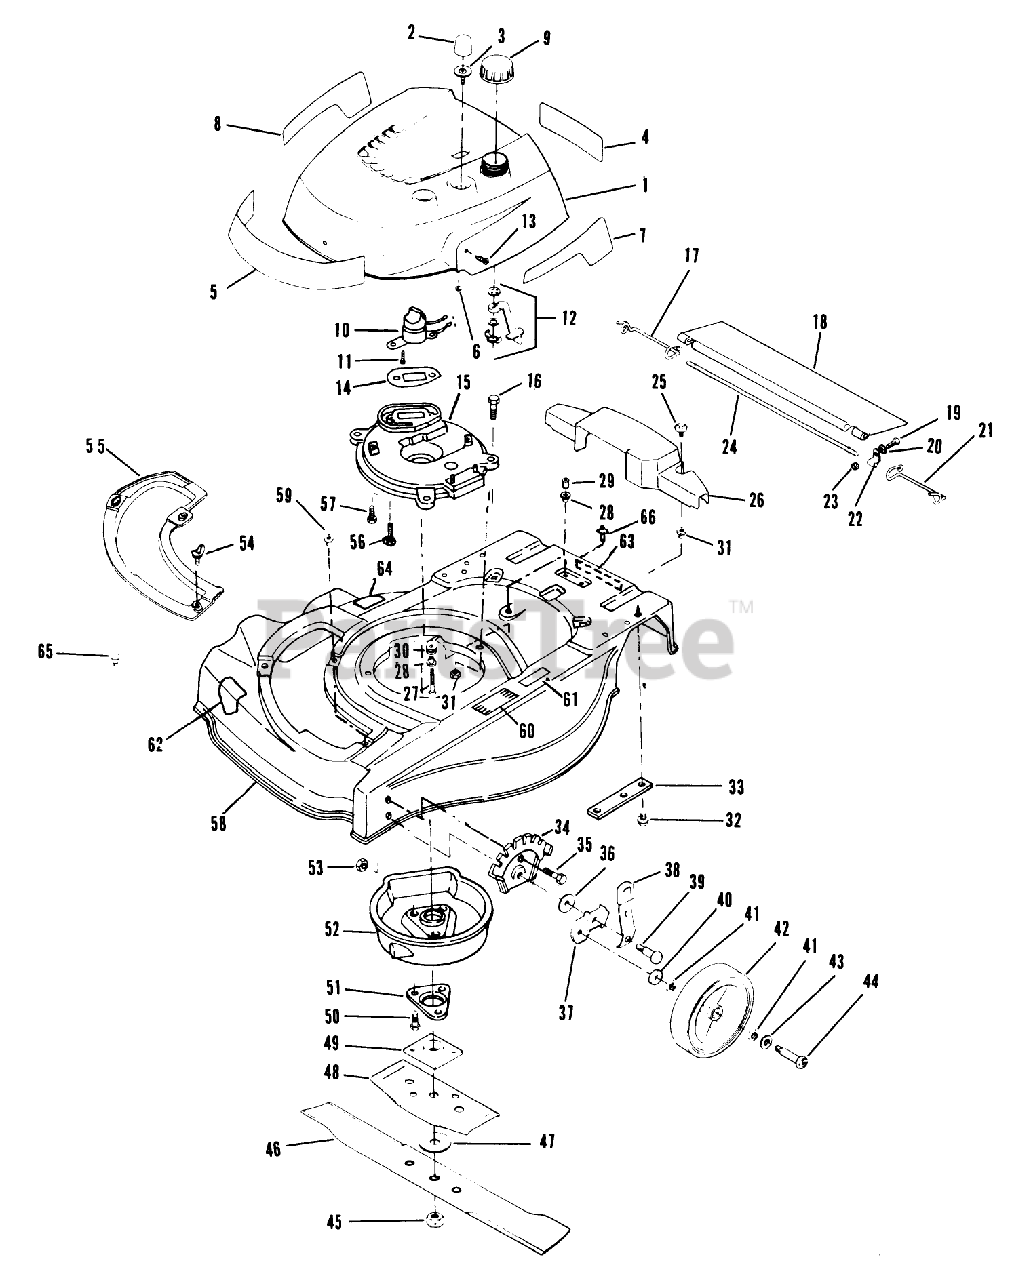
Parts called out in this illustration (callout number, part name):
2	P-BULB LAV-RUB
6	LOCKNUT S
13	SCREW S
15	PLATE,MUFFLER F
16	SCREW
17	SPRING;TRAILING SHIELD RH
20	WASHER F
21	SPRIG T/SHLD ASOC
23	LOCKNUT E
25	SCREW SEMS TRM HEX HD
28	SPACER ECK PRES
29	SPACER
31	NUT-LOCK F
32	SCREW
34	PLATE HGT ADJ TRO
36	WASHER
40	WASHER WROUGHT
41	WASHER
43	SPACER
44	BOLT WHEEL
45	NUT-BLADE
47	WASHER
49	PLATE AND COLLAR ASM
51	SUPPORT F
53	LOCKNUT
54	WING SCREW LAWRE
56	SCREW V
60	PAD FOOT
66	Rivet-Serial Plate
